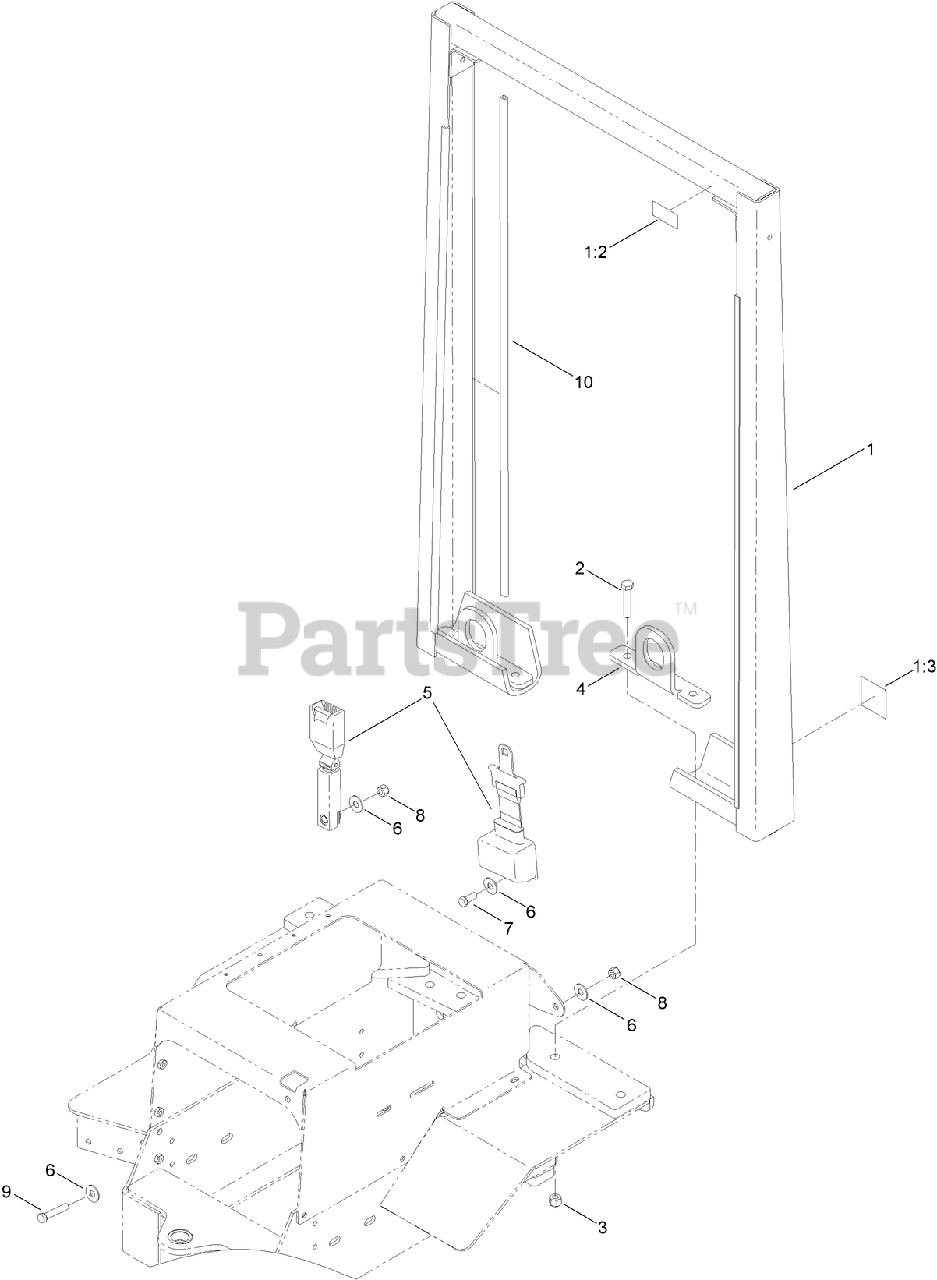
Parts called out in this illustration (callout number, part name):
1	ROPS ASM
1:2	DECAL-ROPS CERTIFICATION
1:3	DECAL-LIFT HERE
2	SCREW-HH
3	NUT-HEX
4	PLATE-LIFT
5	SEAT BELT ASM
6	WASHER-FLAT
7	SCREW-HH
8	NUT-LOCK
9	SCREW-HH
10	TRIM-FIREWALL
